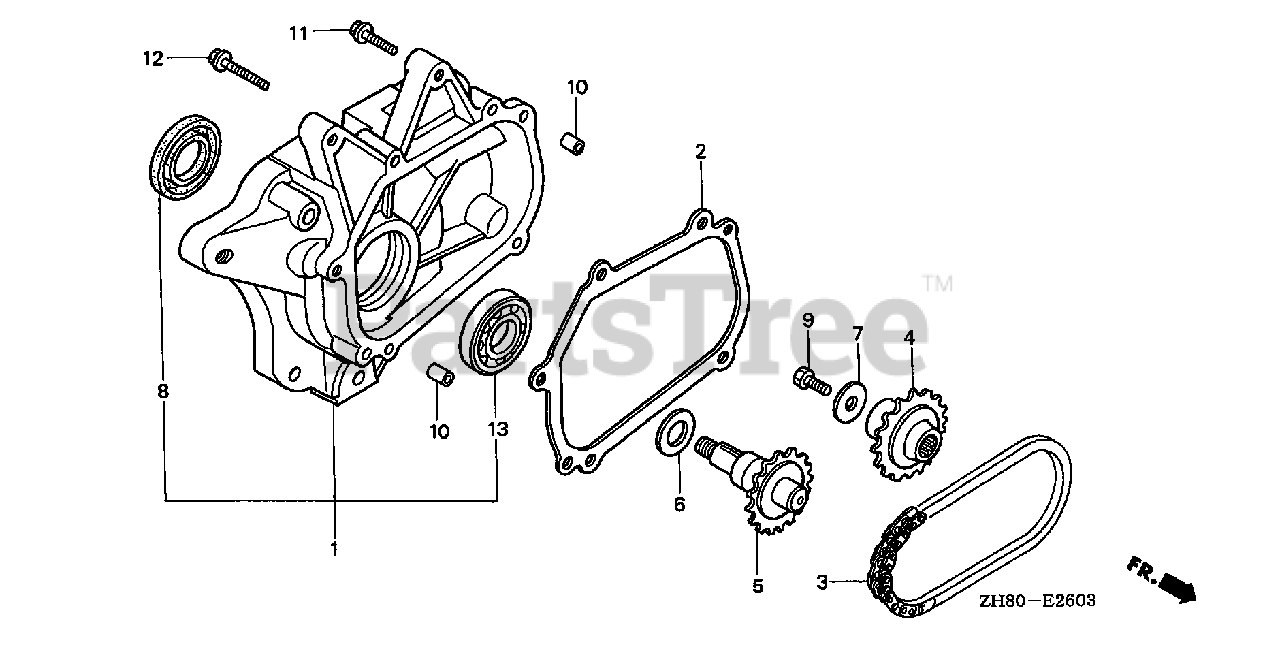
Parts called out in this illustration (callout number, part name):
1	COVER ASSY., CHAIN CASE
2	GASKET, CHAIN CASE COVER
3	CHAIN, P.T.O. DRIVE
4	SPROCKET, DRIVE (17T)
5	SHAFT, P.T.O. (16T)
6	SPRING, THRUST
7	WASHER (8MM)
8	OIL SEAL (25X38X7)
8	OIL SEAL (25X38X7) (ARAI)
9	BOLT, HEX. (8X25)
10	PIN, DOWEL (8X14)
11	BOLT, FLANGE (8X35)
12	BOLT, FLANGE (8X55)
13	BEARING, RADIAL BALL (6005)
